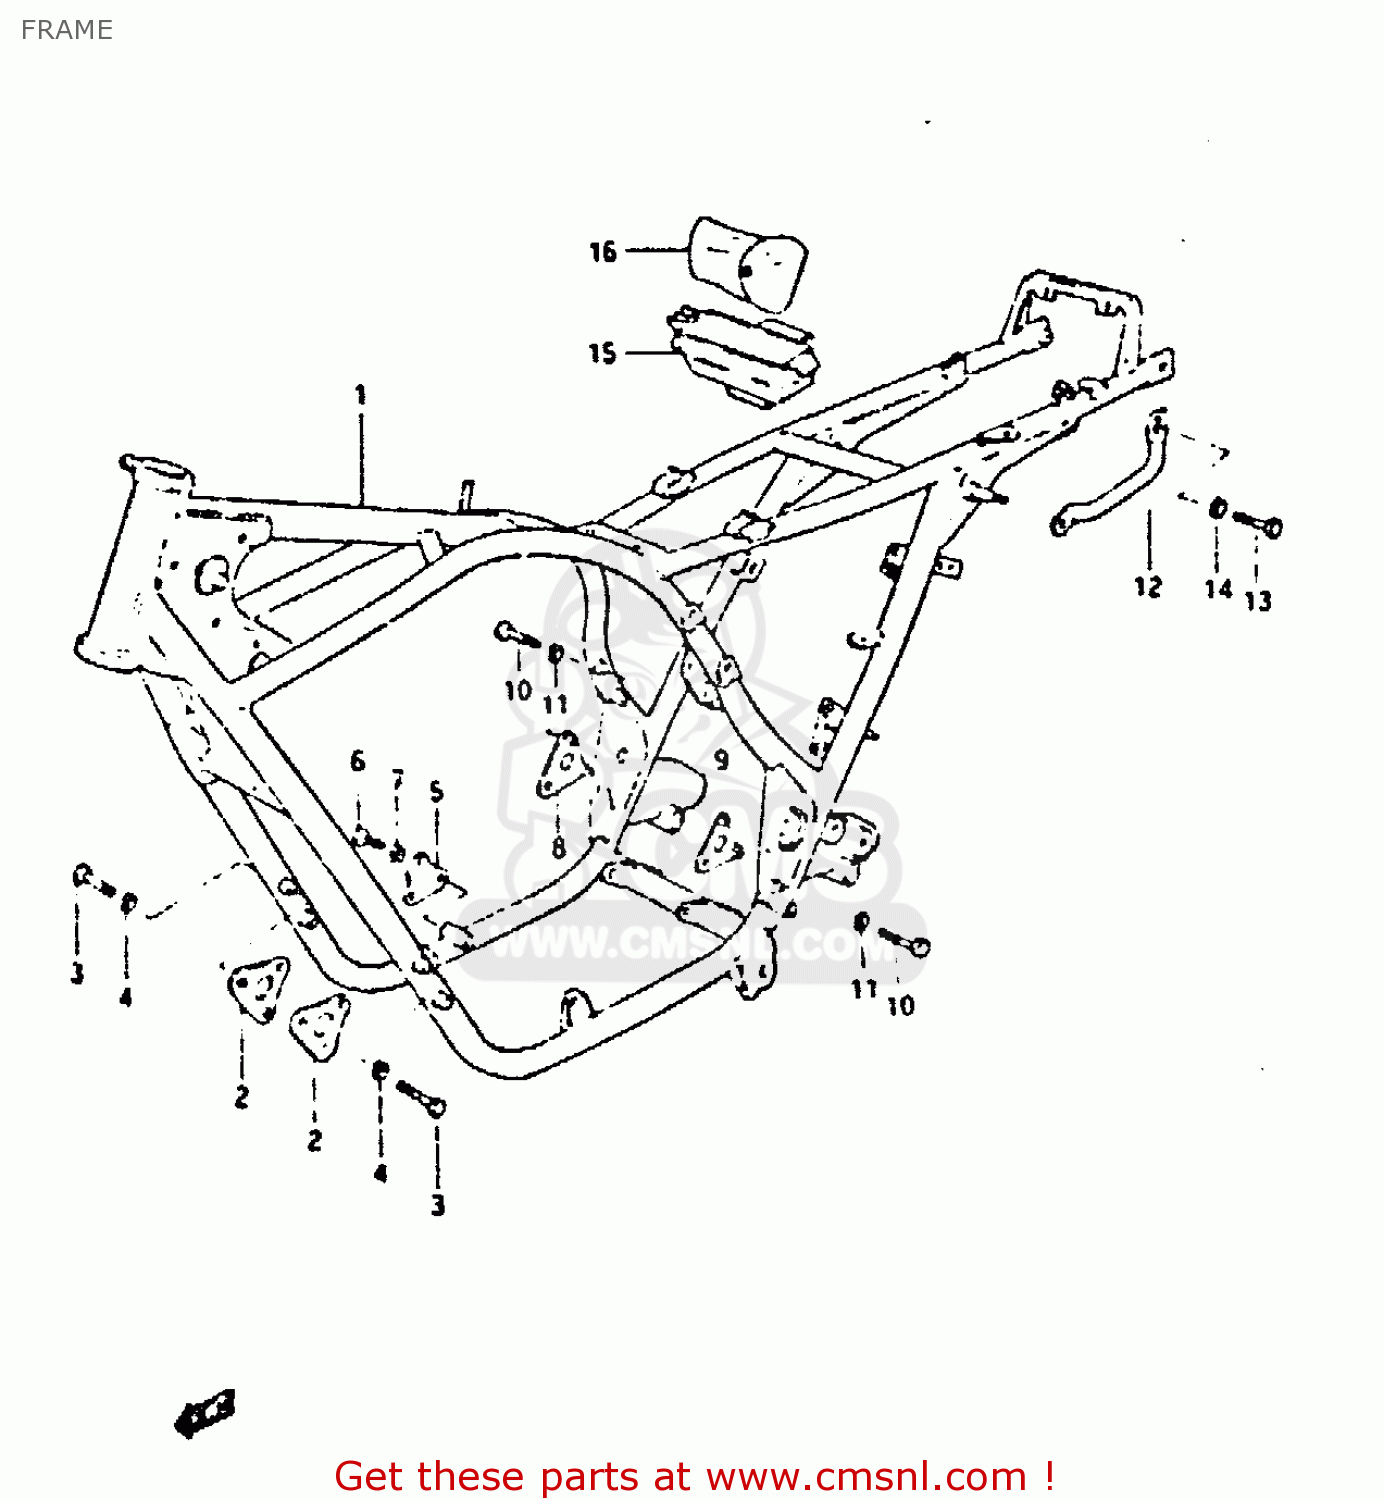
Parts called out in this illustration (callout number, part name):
1	FRAME
2	PLATE,ENGINE MOUNTING NO
3	BOLT
4	LOCK WASHER
5	BOLT,CRANKCASE ADJUST
6	BOLT, UPPER
7	LOCK WASHER
8	PLATE,ENGINE MOUNTING NO
9	PLATE,ENGINE MOUNTING
10	BOLT
11	LOCK WASHER
12	GRIP,FRAME HANDLE
13	BOLT
14	WASHER
15	HOLDER,TOOL
16	TOOL SET
